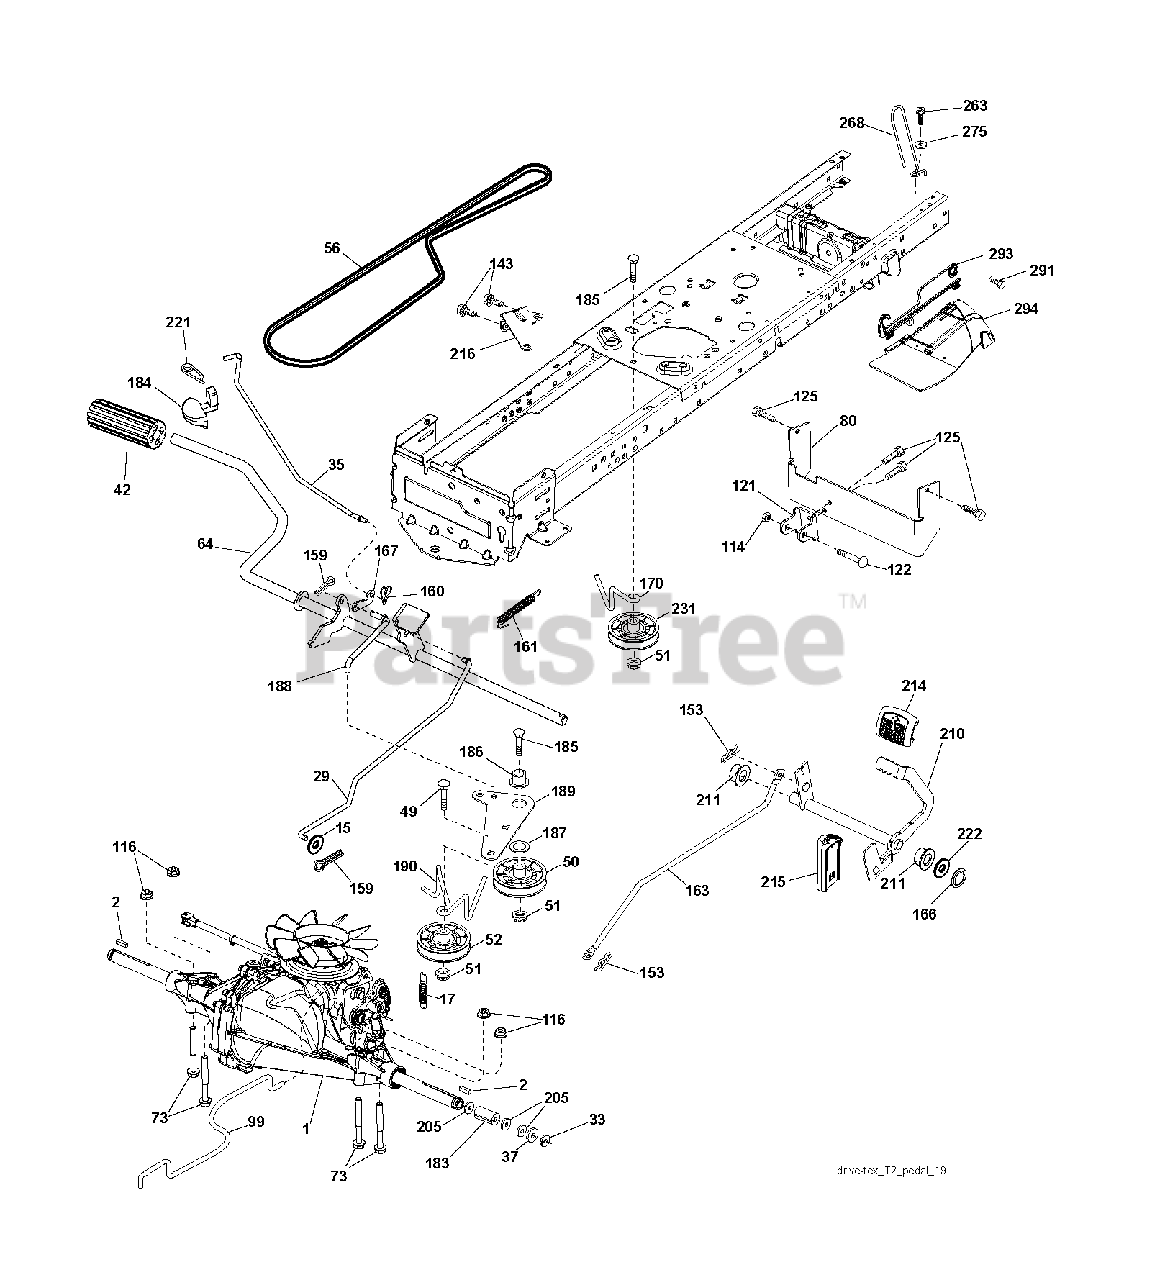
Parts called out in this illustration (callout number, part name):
2	SQUARE KEY
17	SPRING.BRAKE.HG3000/3500
29	ROD BRAKE
33	E-RING LT
35	ROD, BRAKE, PARK
42	PEDAL COVER T
49	BOLT
50	IDLER.FLAT.910.OFFSET
51	NUT LOCK FLG 3/8-16 UNC
52	IDLER.V-GROOVE.910.OFFSET
64	SHAFT.ASM.PEDAL.BRK.CNTR
73	BOLT HEX 5/16-18 GR 5
80	STRAP.TORQUE.FS.T2
99	ROD.ASM.BYPASS.SPRING.T2.FS
114	NUT.71038.31-18.HEX.NYLOCK
116	NUT LOCK HEX FLANGE 5/16-18
121	BRACKET STRAP TORQUE
122	BOLT.5/16-18X2.5
125	SCREW
153	RETAINER M
159	COTTER PIN
160	RETAINER CLIP
161	SPRING, RETURN LT
163	ROD.CONTROL.PCH.T2.TEX
166	NUT.PUSH.625.2006
167	LATCH.BRAKE.SPRING
170	KEEPER.CENTER SPAN.1.688
183	SPACER, AXLE PVST
184	HANDLE PARKING BRAKE
186	SPACER.RETAINER
187	WASHER 12/32X2X10GA
188	LINK.CLUTCH.GROUND.DRIVE
189	BELLCRANK.GROUND.DRIVE.TEX.
190	KEEPER.BELLCRANK.DRIVE
210	ROCKER.ASM.PEDAL.CONTR
211	BEARING.NYLON
214	PAD PEDAL FORWARD
215	PEDAL.REVERSE.TEX.GT.4
216	BRACKET.PULLEY.IDLER.W/TEX
221	RETAINER.SPRING.CLIP.H
222	WASHER 21/32 X 1-1/4 X 10 GA.
231	IDLER.V-GROOVE.1.688.OFFSET
263	SCREW, 3/8-16X3/4
275	WASHER
291	SHOULDER BOLT 5/16-18TT
